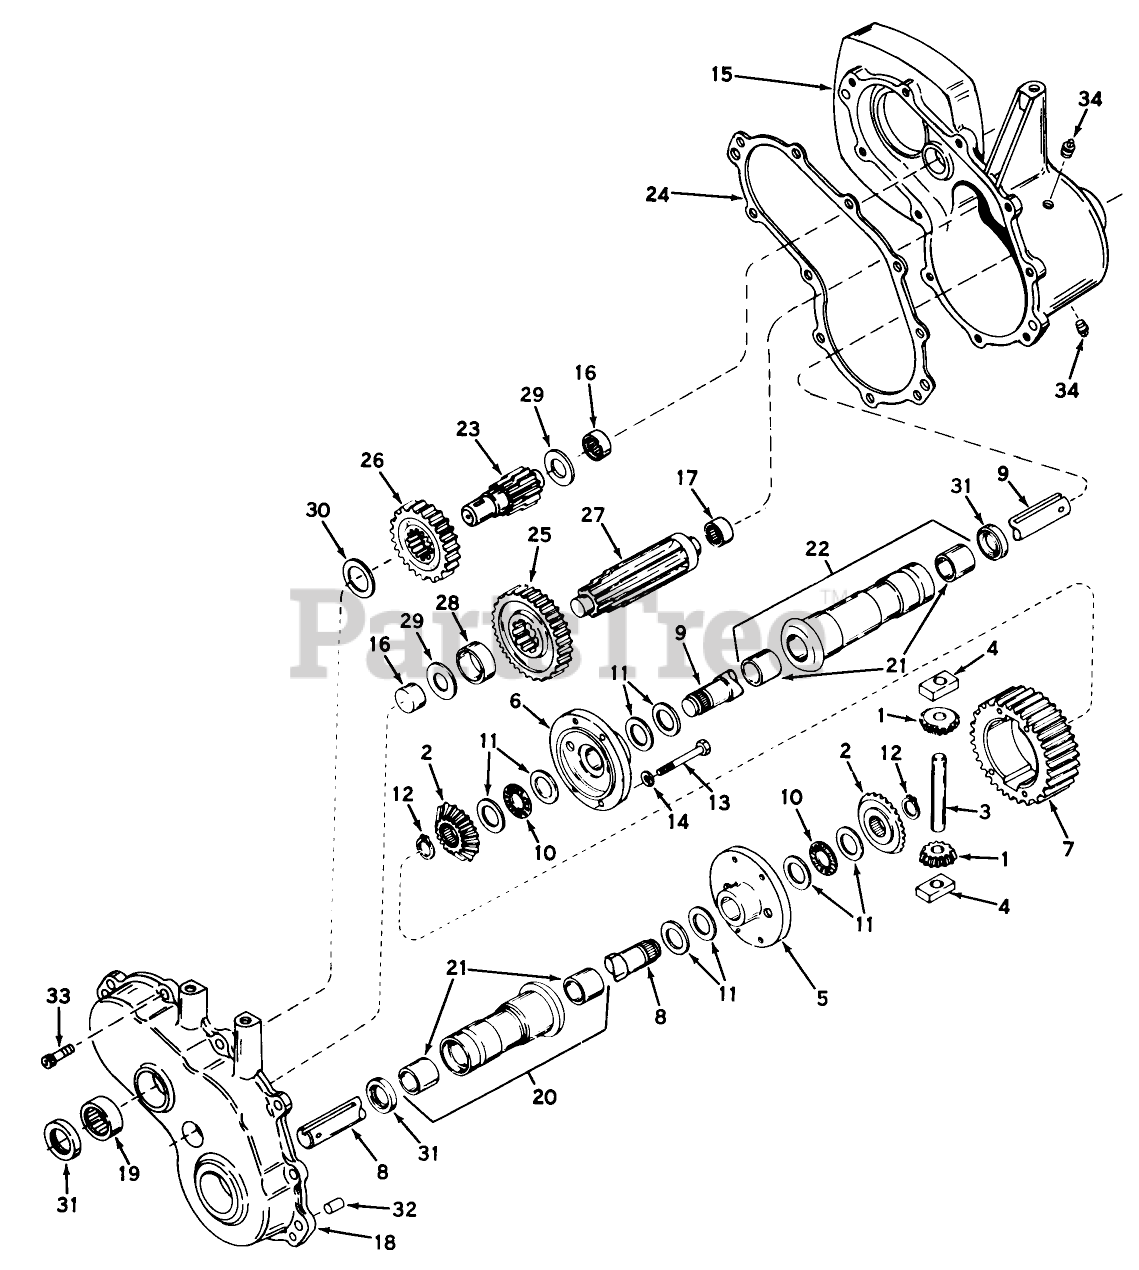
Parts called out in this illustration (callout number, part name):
1	Pinion-Bevel
2	Gear-Bevel
3	Pin-Drive
4	Biock-Drive
5	Carrier, Differential
6	Carrier, Differential
7	Gear, Ring
8	Axle, L.H.
9	Axle, R.H.
10	Bearing-Thrust
11	Washer
12	Ring-Snap
13	Screw-Hex Hd.
14	Lockwasher
15	Case Assy. (Incl. Nos. 16 17)
16	Bearing
17	Bearing-Needle
18	Cover Assy. (Incl. Nos. 16 19)
19	Bearing Needle
20	Housing Bushing Assy., L.H. (Incl. No. 21)
21	Bushing
22	Housing Bushing Assy., R.H. (Incl. No. 21)
23	Shaft, Brake
24	Gasket
25	Gear-Output
26	Gear-Spur
27	Shaft, Output
28	Spacer
29	Washer
30	Washer
31	Seal-Oil
32	Dowel Pin
33	Screw, Hex hd. self tapping
